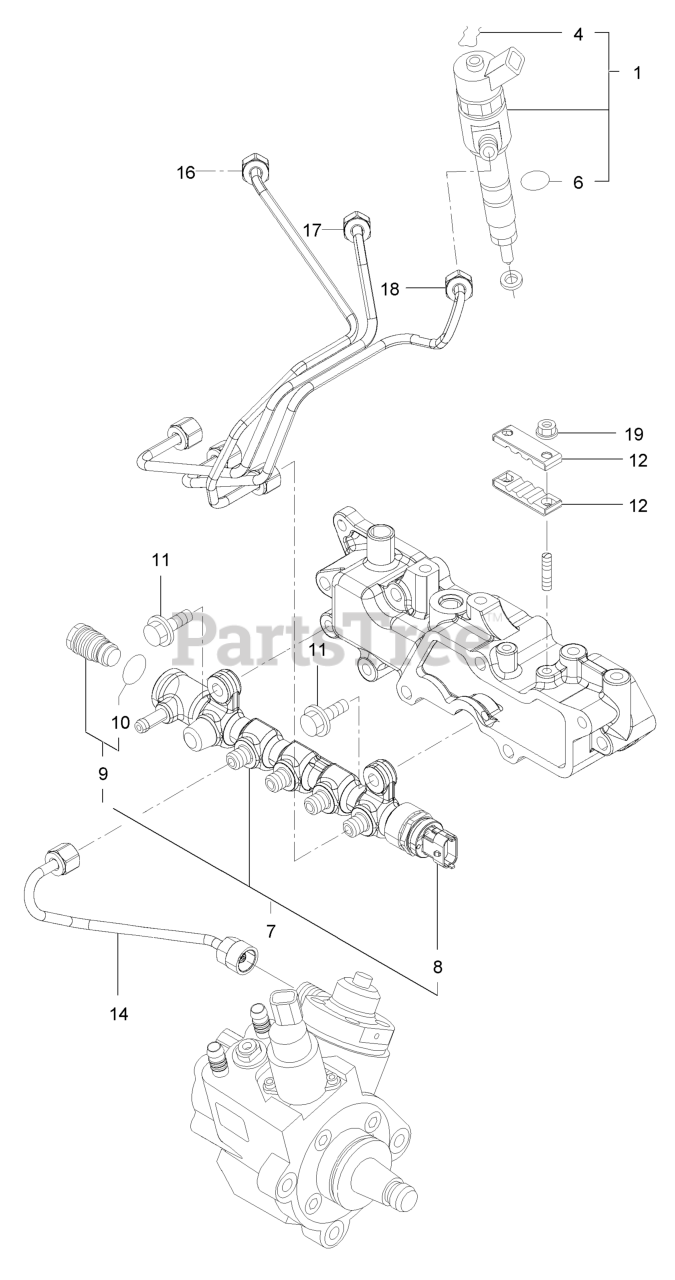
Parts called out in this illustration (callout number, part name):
1	Injector ASM
4	Ring-Retaining
7	Rail ASM
8	Sensor-Pressure, Rail
9	Valve ASM
12	Retainer
14	Rail In Pipe ASM
16	Injection Pipe ASM
17	Injection Pipe ASM
18	Injection Pipe ASM
